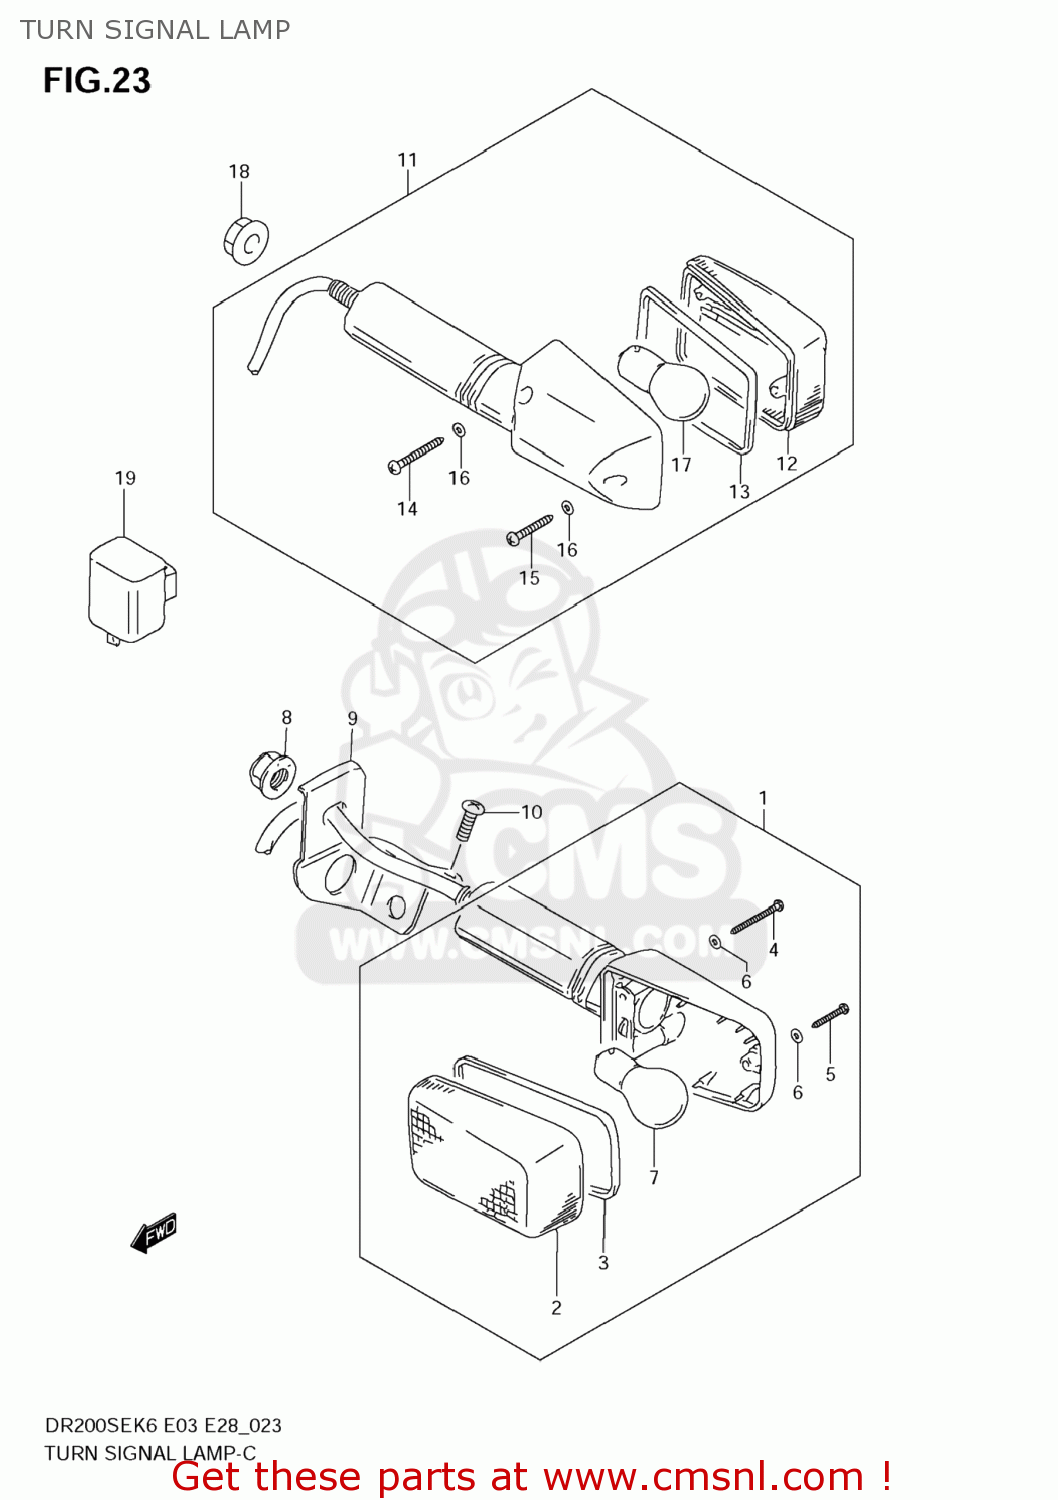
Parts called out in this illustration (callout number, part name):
1	LAMP ASSY,FR TURN SIGNAL
2	LENS
3	GASKET (NAS)
4	SCREW(3X30)
5	SCREW
6	GASKET (NAS)
7	BULB(12V21W)
8	NUT
9	BRACKET,FR TURN,R
10	SCREW
11	LAMP ASSY,RR TURNSIGNAL
12	LENS
13	GASKET (NAS)
14	SCREW(3X30)
15	SCREW
16	GASKET (NAS)
17	BULB(12V21W)
18	NUT
19	RELAY ASSY,TURNSIGNAL
